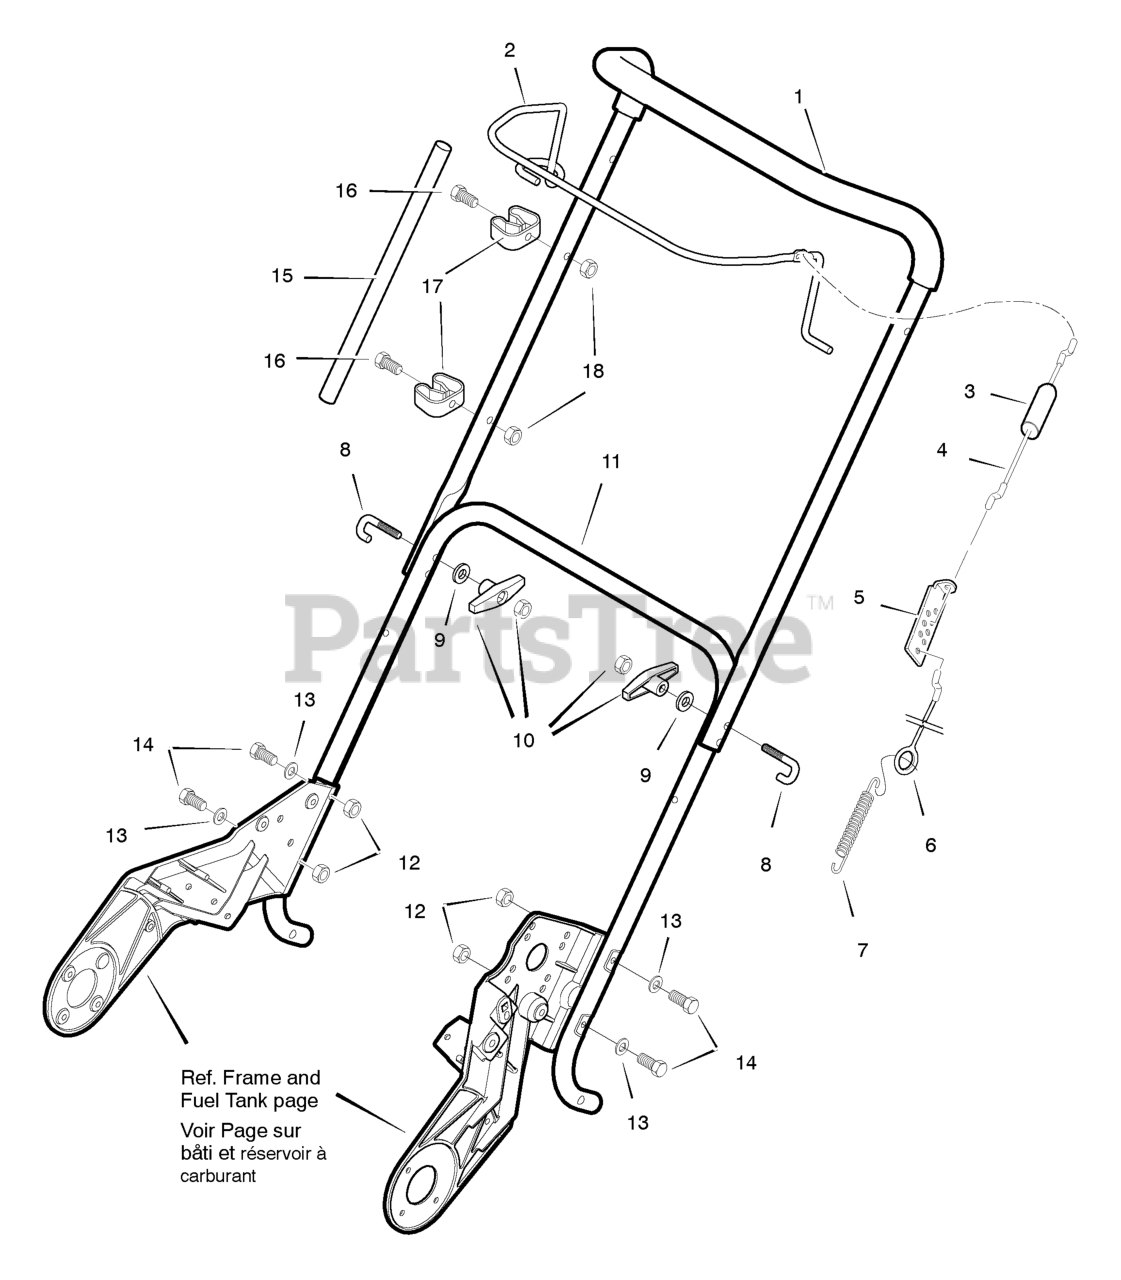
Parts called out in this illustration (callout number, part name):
1	Handle, Upper (Foam)
2	Control, Bail
3	Boot, Clutch Spring
4	Cable, Upper Control
5	Bracket, Control Adjust
6	Cable, Lower Control
10	Knob, Wing
11	Handle, Lower
13	Washer
14	Screw, 1/4-20 x1.25
15	Tool, Clean-out
17	Clip, Retainer
